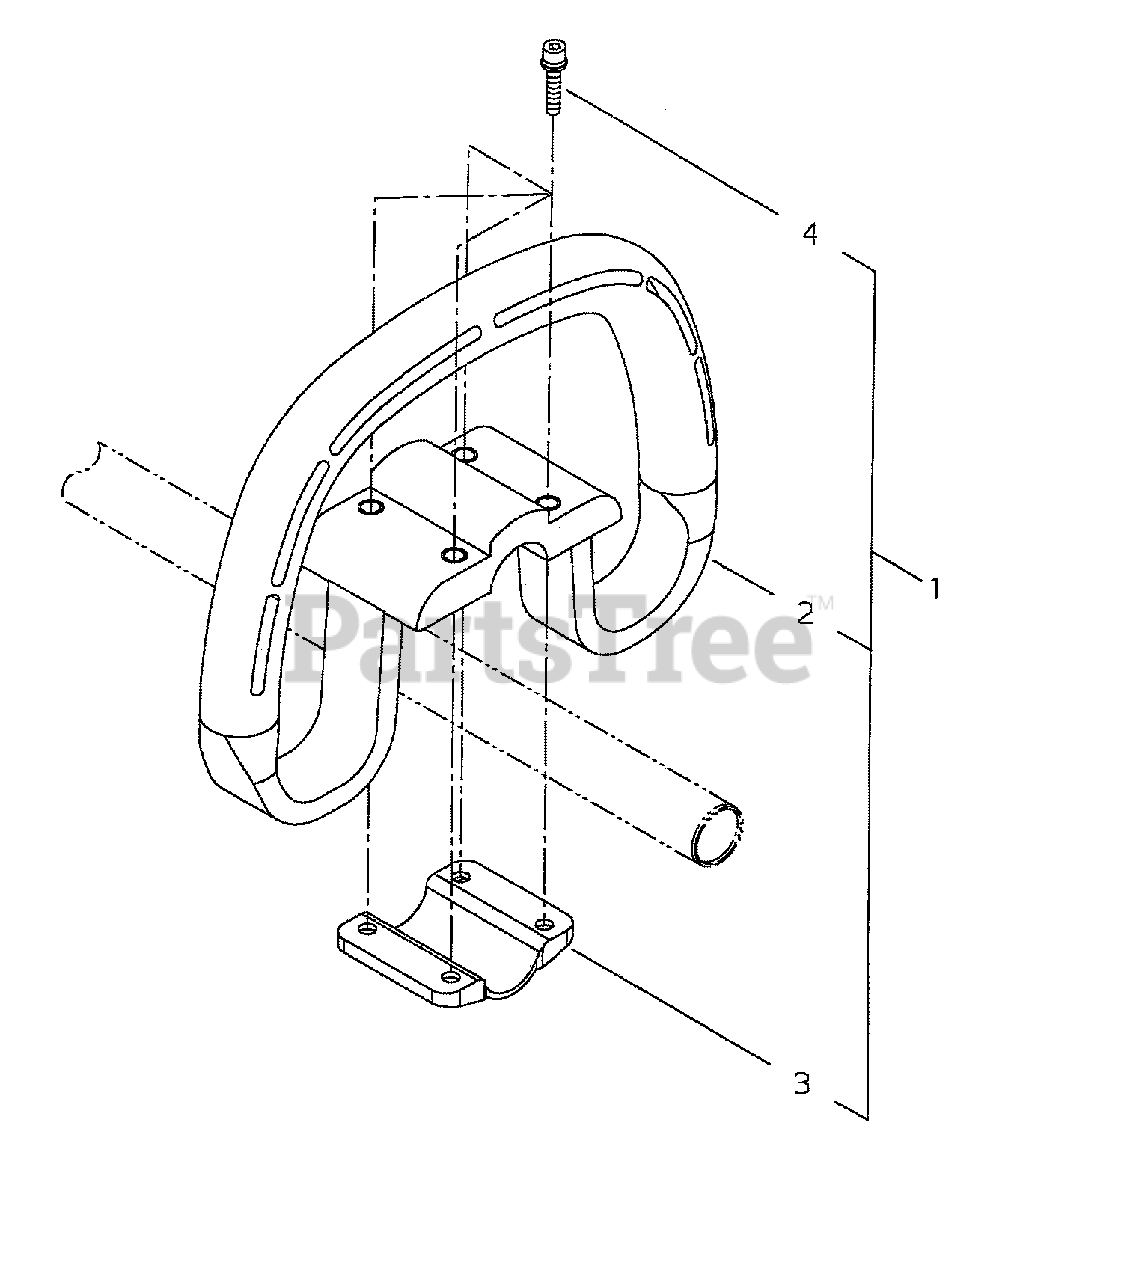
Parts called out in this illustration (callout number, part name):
1	HANDLE ASSY
2	HANDLE, SUPPORT
3	BRACKET, MOUNTING
4	BOLT M5×25
